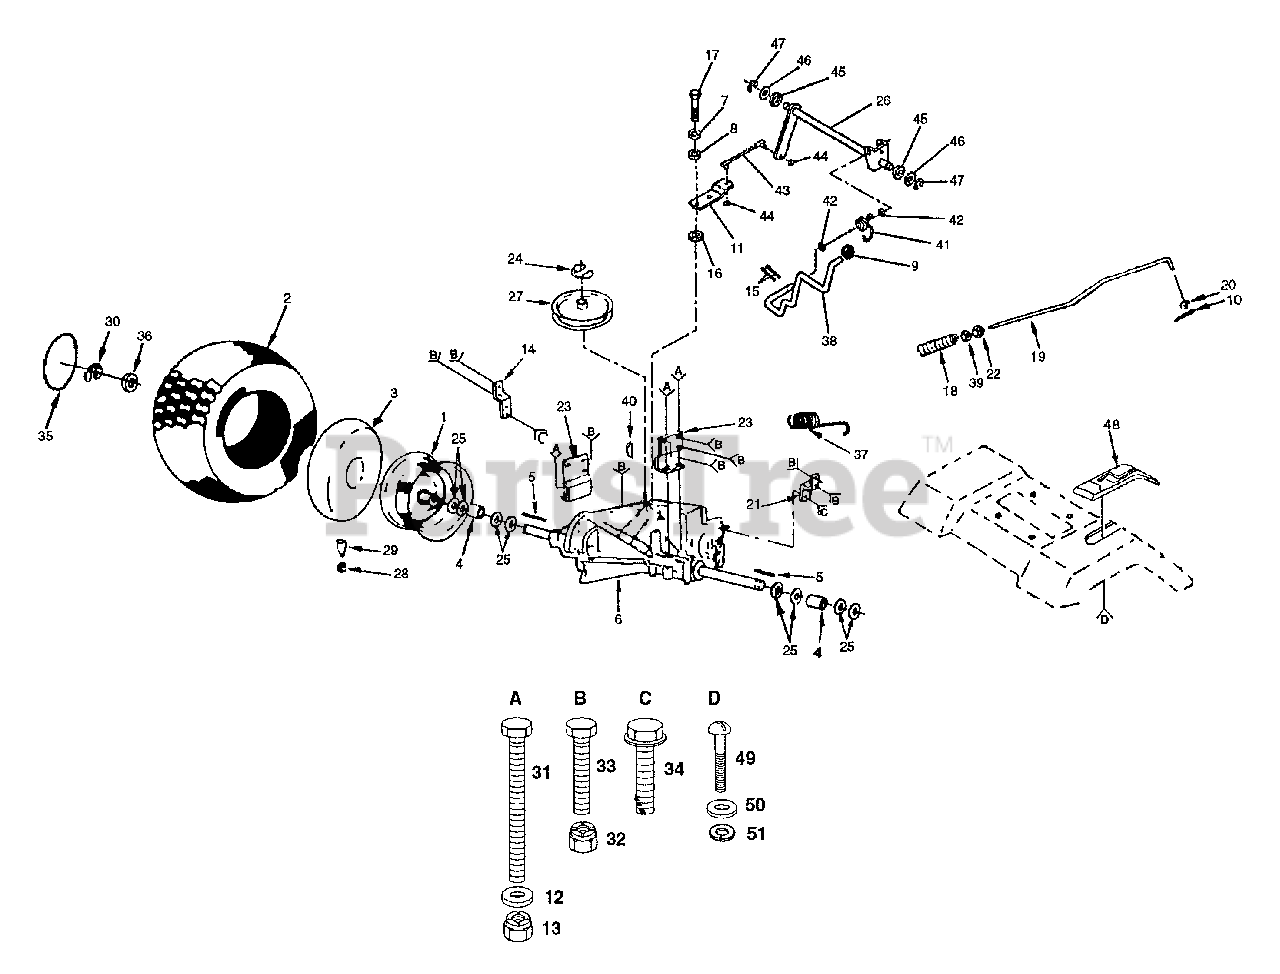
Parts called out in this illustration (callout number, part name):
1	Rim Assembly
2	Tire
3	Tube, Tire
4	Spacer, Split
5	Key, Square 3/16 x 2
6	Transaxle, Peerless
7	Washer, Lock 1/4
8	Washer 9/32 x 3/4 x 10 Ga.
9	Knob, Control
10	Cotter Pin 1/8 x 3/4
11	Arm, Shift
12	Washer 11/32 x 11/16 x 16 Ga.
13	Nut, Crownlock 5/16-18
14	Strap, Torque L.H.
15	Pin, Cotter 1/8 x 1
16	Washer, Shift Plate
17	Bolt, Hex 1/4-28 x 3/4 Gr. 8
18	Spring, Rod, Brake
19	Rod, Brake
20	Washer 13/32 x 13/16 x 16 Ga.
21	Strap, Torque R.H.
22	Nut, Hex Jam 3/8-16
23	Bracket, Transaxle
24	Ring, Retainer
25	Washer 25/32 x 1-1/4 x 16 Ga.
26	Shaft Assembly, Shifter
27	Pulley, Input Transaxle
28	Cap, Valve
29	Stem, Valve
31	Bolt, Hex 5/16-18 x 2-1/2
32	Nut, 3/8-16
33	Bolt, Hex 3/8-16 x 3/4
34	Screw Hex Washer Hd. Thd. Form. Type TT 5/16-18 UNC x 3/4
35	Cover, Wheel
36	Washer 25/32 x 1-5/8 x 16 Ga.
37	Spring, Brake Return
38	Rod, Shifter
39	Locknut, Hex W/Wsh. 3/8-16 UNC
40	Key, Woodruff #9 3/16 x 3/4
41	Spring, Torsion
42	Washer 17/32 x 3/4 x 16 Ga.
43	Rod, Link, Shift
44	Nut, Nylock 1/4-28
45	Bushing, Pivot
46	Washer, Shim .53 x 1.25 x .0598
48	Console Shift
49	Screw #8 x 3/8
50	Washer 3/16 x 7/16 x 18 Ga.
51	Washer Lock # 8
